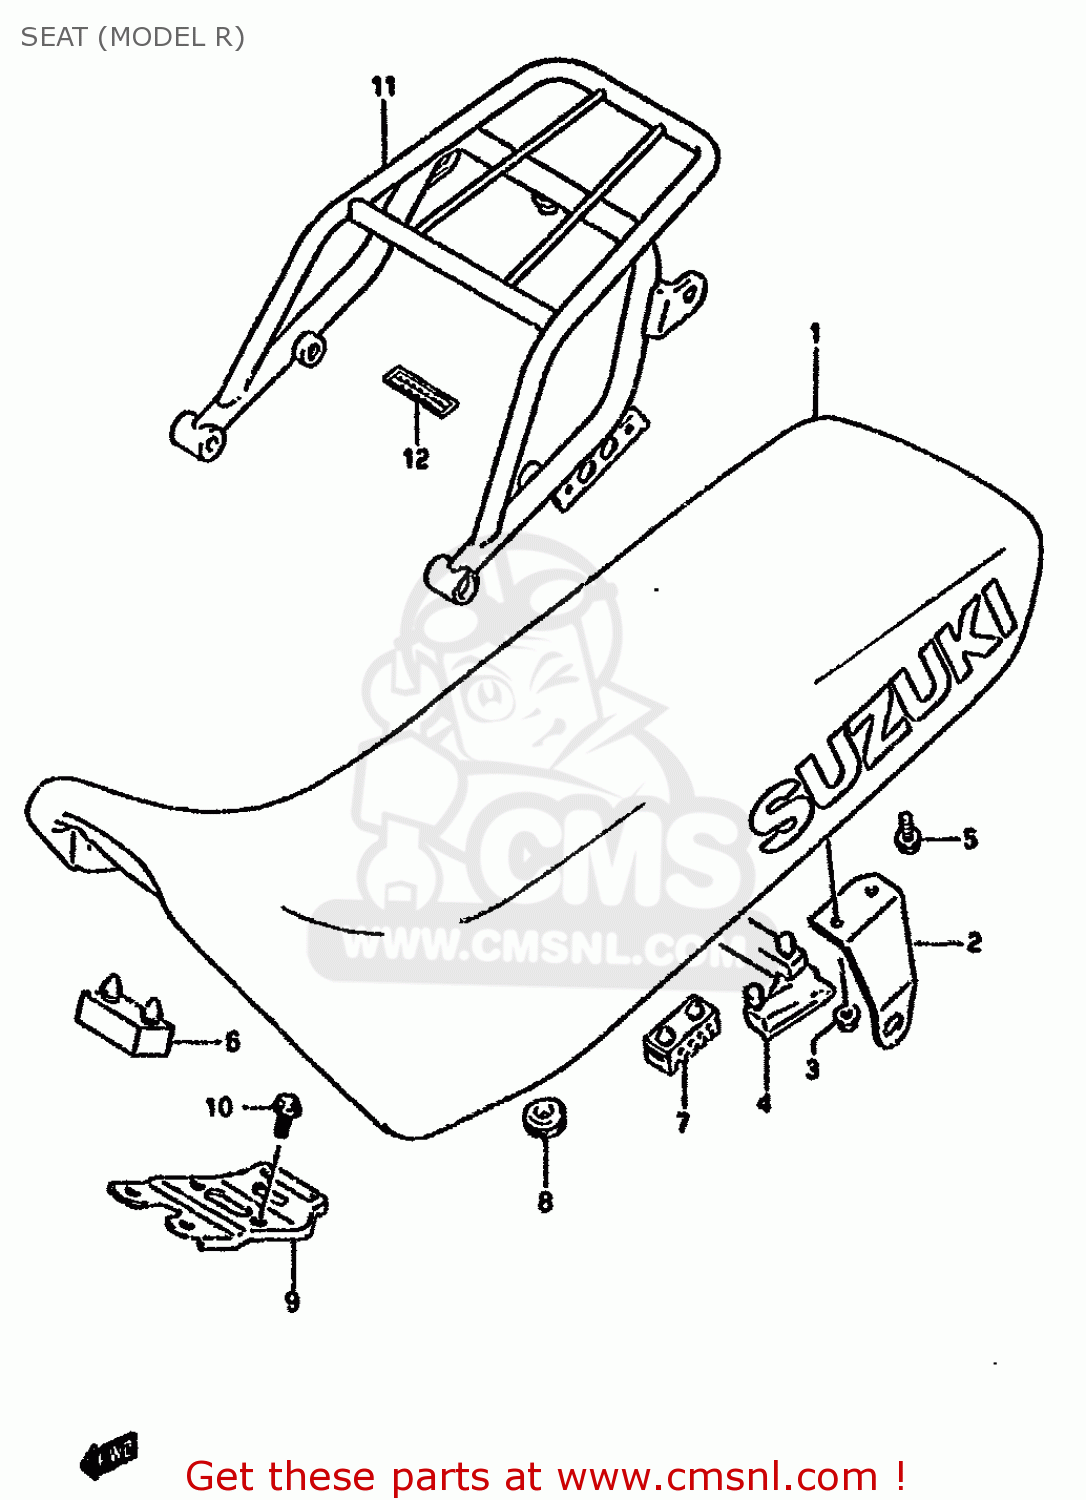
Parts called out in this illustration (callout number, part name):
1	SEAT SET
2	BRACKET,SEAT,R
3	NUT
4	CUSHION
5	BOLT
6	CUSHION
7	CUSHION,SEAT(40X20X15)
8	CUSHION
9	PLATE,SEAT FR HOOK
10	BOLT
11	BOLT
12	WASHER
13	CARRIER
